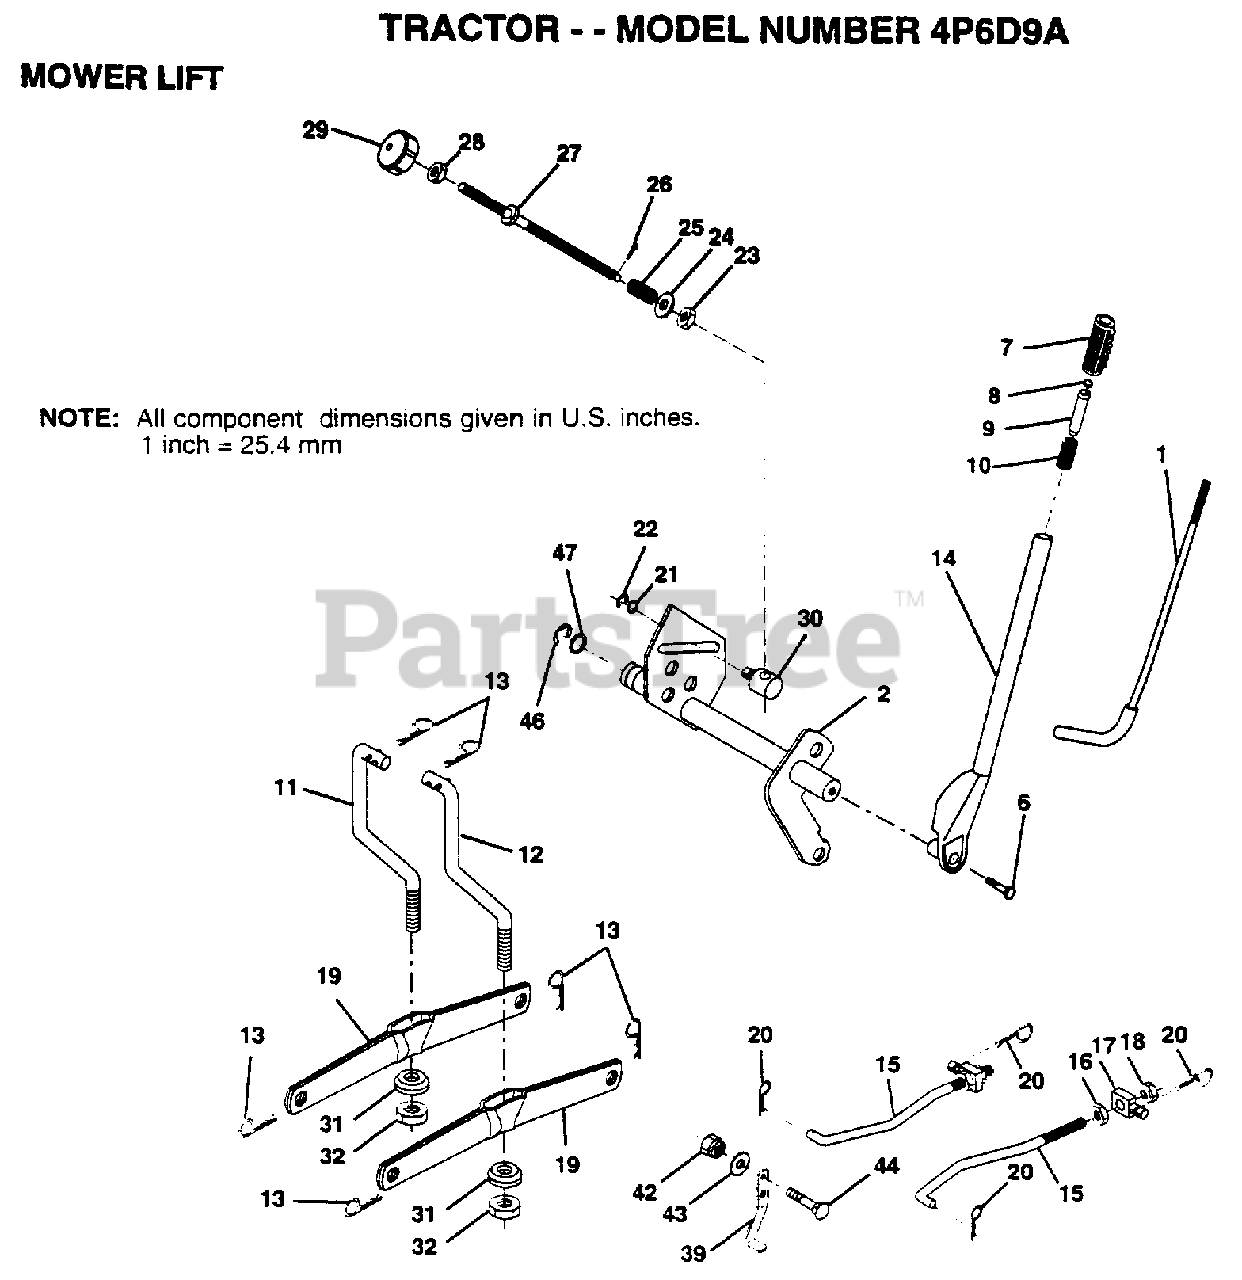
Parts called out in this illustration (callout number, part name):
1	LEVER ROD LT
2	SHAFT LIFT W/IND
6	"BOLT,HEX"
7	GRIP
10	SPRING T
11	LINK.LIFT.LH.GTV
12	LINK.LIFT.RH.GTV.
15	LINK.FRONT
16	NUT
17	TRUNION
18	NUT.LK.W/WSH.1/2.
19	ARM SUSP REAR
20	RETAINER.SPRING
21	WASHER
22	KLIP RING
23	NUT T
24	WASHER
25	SPRING.COMP.INF.H
27	ROD.ADJ.LIFT
28	NUT
29	KNOB INF 3/8-16
30	TRUNION LT
31	BEARING PVT LH
32	NUT.CROWNLOCK.3/8
39	STOP.OVER.CENTER
43	WASHER GT
44	BOLT
46	E-RING
47	WASHER
